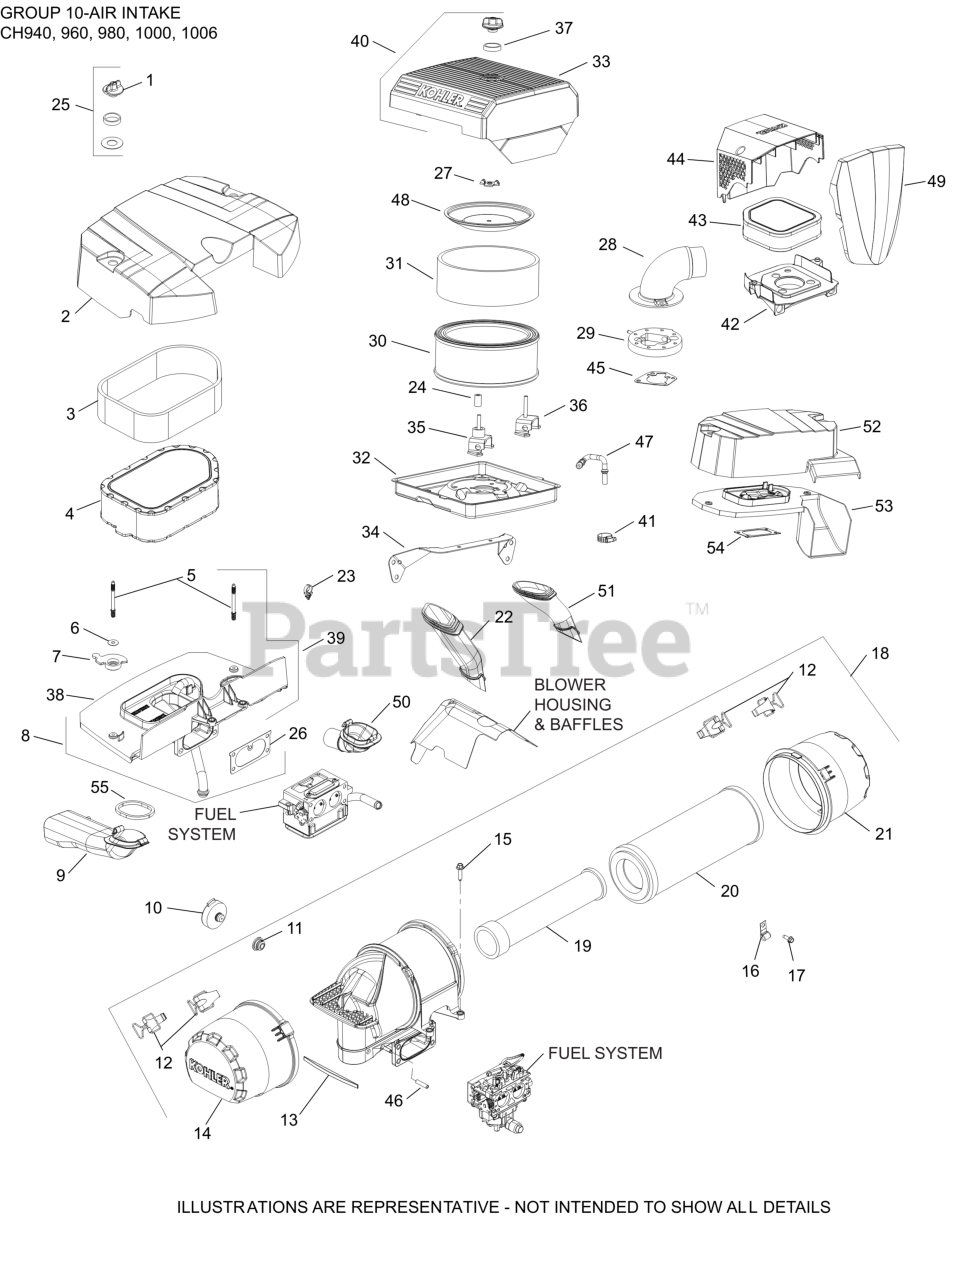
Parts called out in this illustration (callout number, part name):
1	KNOB, COVER
4	ELEMENT, AIR FILTER (LPAC)
5	STUD, AIR CLEANER BASE
25	KIT, KNOB W/SEAL
52	BASE, AIR CLEANER ASSEMBLY
53	COVER, AIR CLEANER
54	GASKET, AIR CLEANER ELBOW
